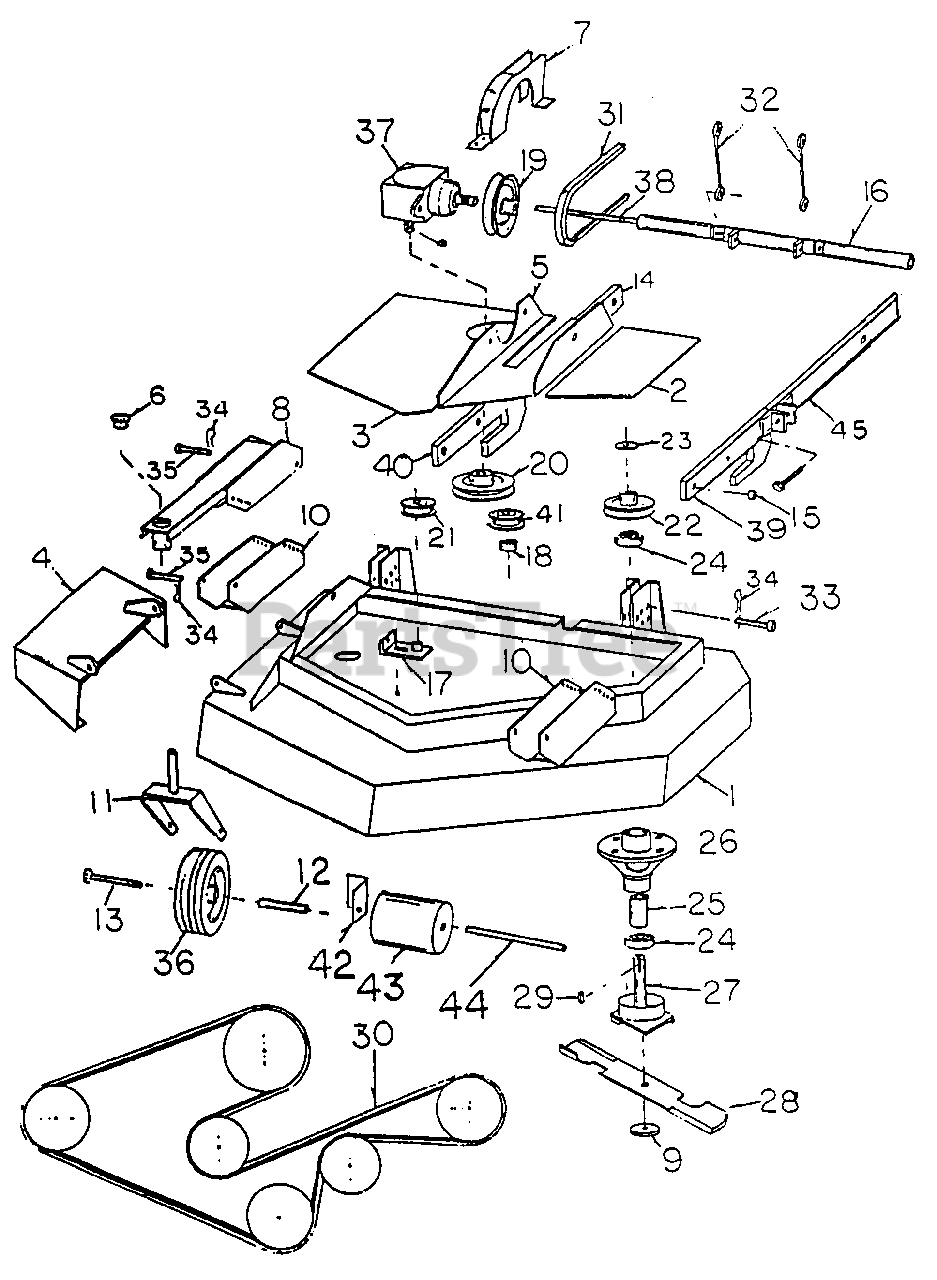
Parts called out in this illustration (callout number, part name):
3	COVER (LARGE)
4	FOOT GUARD
5	GEAR BOX MOUNT
6	GAGE WHEEL BUSHING
7	BELT GUARD
8	GAGE WHEEL MOUNT
10	BRACKET, GAGE WHEEL MOUNT
11	FORK, GAGE WHEEL
12	AXLE, GAGE WHEEL
13	GAGE WHEEL BOLT
14	DECK LIFT ARM BACK ADJUSTABLE
15	BUSHING, DECK LIFT ARM
18	SPACER, IDLER
19	PULLEY, GEAR BOX
20	PULLEY, GEAR BOX
21	PULLEY, IDLER TIGHTENER
22	PULLEY, SPINDLE
23	WASHER, SPINDLE
24	BEARING, SPINDLE
25	SPACER, SPINDLE
26	HOUSING, SPINDLE
27	SHAFT, SPINDLE
29	KEY, SPINDLE
35	PINS, GAGE WHEEL
38	CROSS BAR PI
39	DECK LIFT ARM FRONT ADJUSTABLE L.H.
40	DECK LIFT ARM FRONT ADJUSTABLE R.H.
42	ROLLAR BRACKET
45	DECK LIFT ARM BACK ADJUSTABLE
